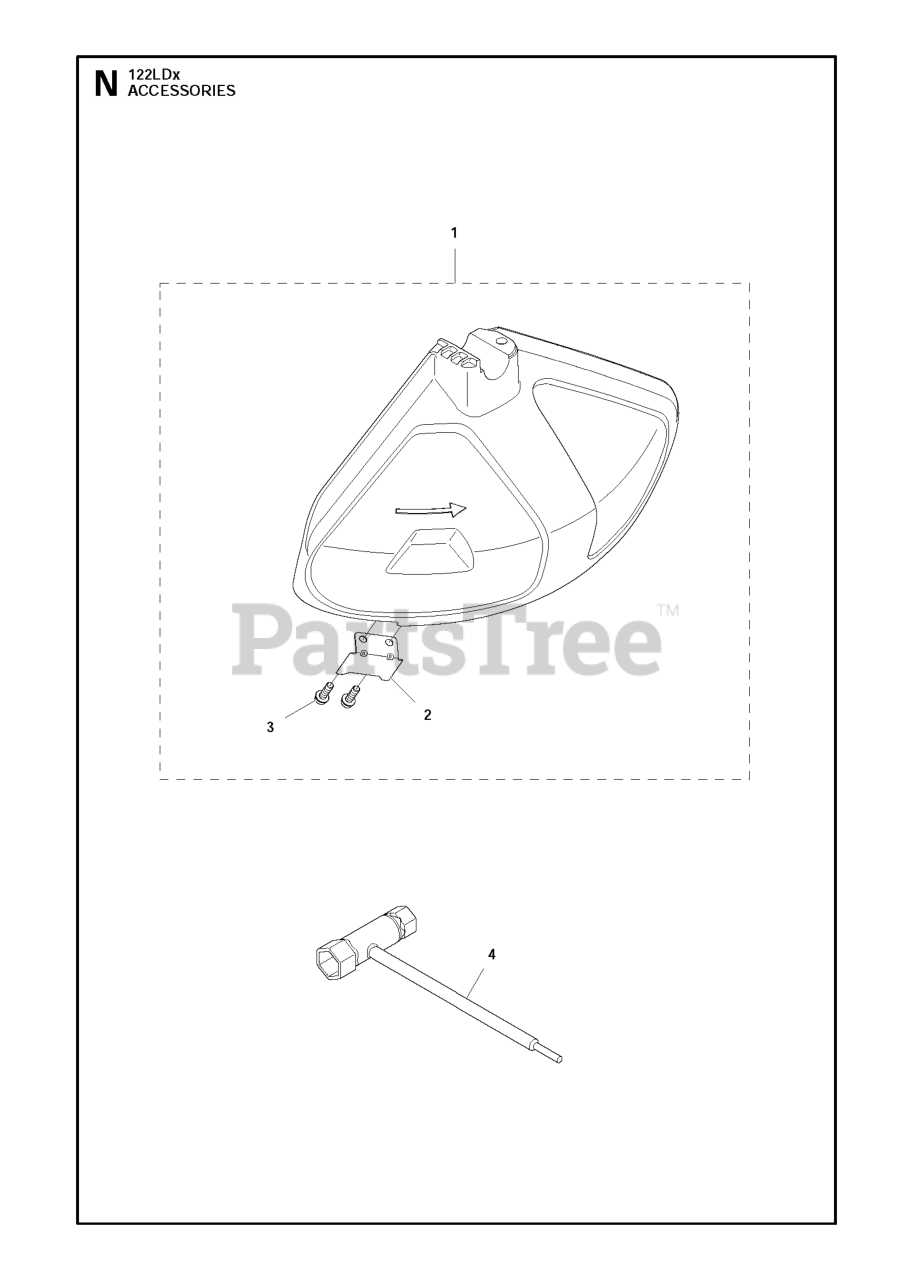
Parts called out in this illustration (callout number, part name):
1	KIT COBI SHIELD
2	LINE LIMITER
4	COMBINATION WRENCH
